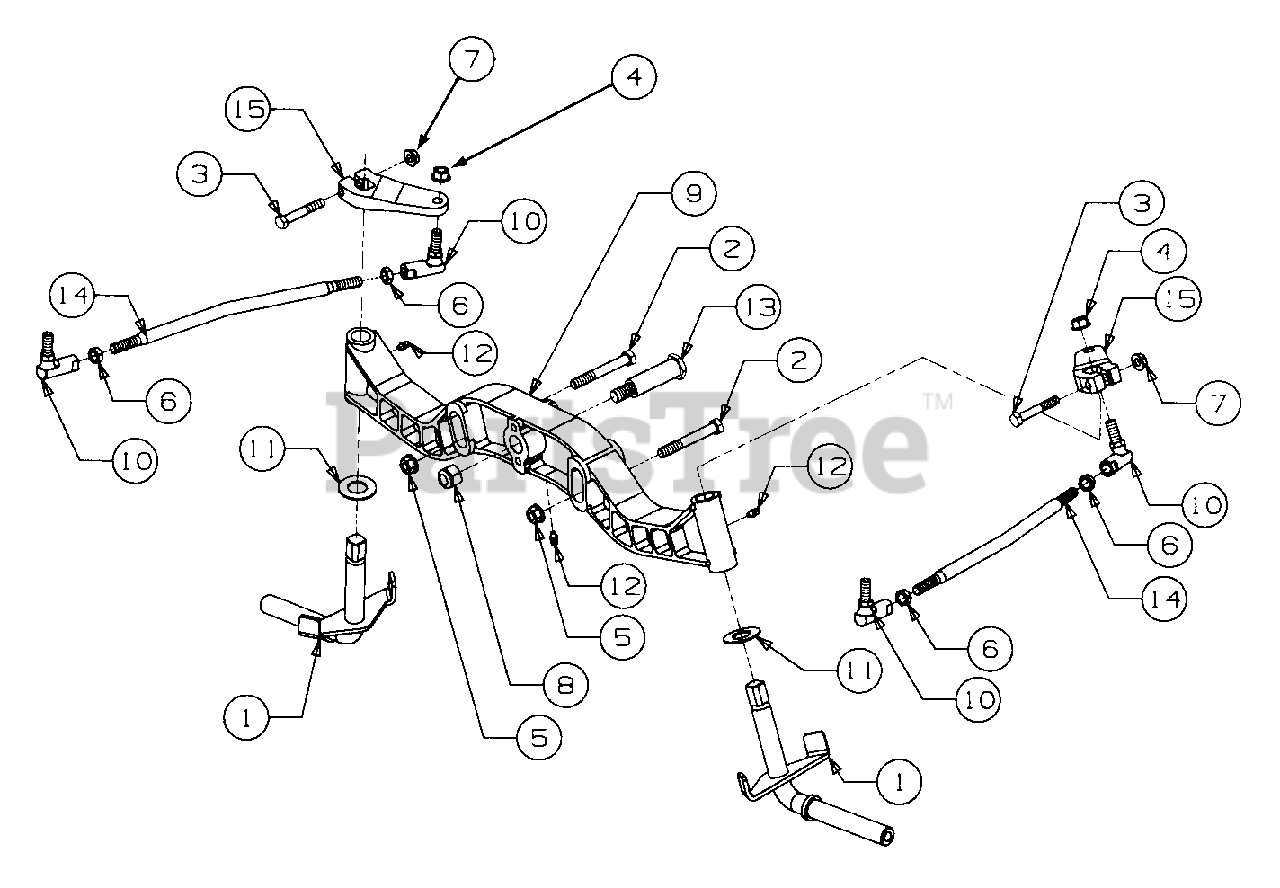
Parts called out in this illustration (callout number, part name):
1	Knuckle Assembly, Steering
2	Screw, Hex Cap, 3/8-16 x 2.75 GR8
3	Screw, Hex Cap, 5/16-18 x 2 GR5
4	Nut, Hex Lock, 3/8-24 GR5
5	Nut, Hex Flanged Lock, 3/8-16
6	Nut, Hex Jam, 3/8-24 GR2
7	Nut, Hex Flange Top Lock, 5/16-18
8	Nut, Hex Top Nylon Lock, 1/2-13
9	Axle, Front Pivot
10	Joint, Ball, 3/8-24
11	Washer, Flat, .760 x 1.49 x .06 Thk.
12	Fitting, Lube, 3/16 Drive Type
13	Bolt, Pivot Shoulder, 3/4 Dia x 2.23
15	Arm, Steering
